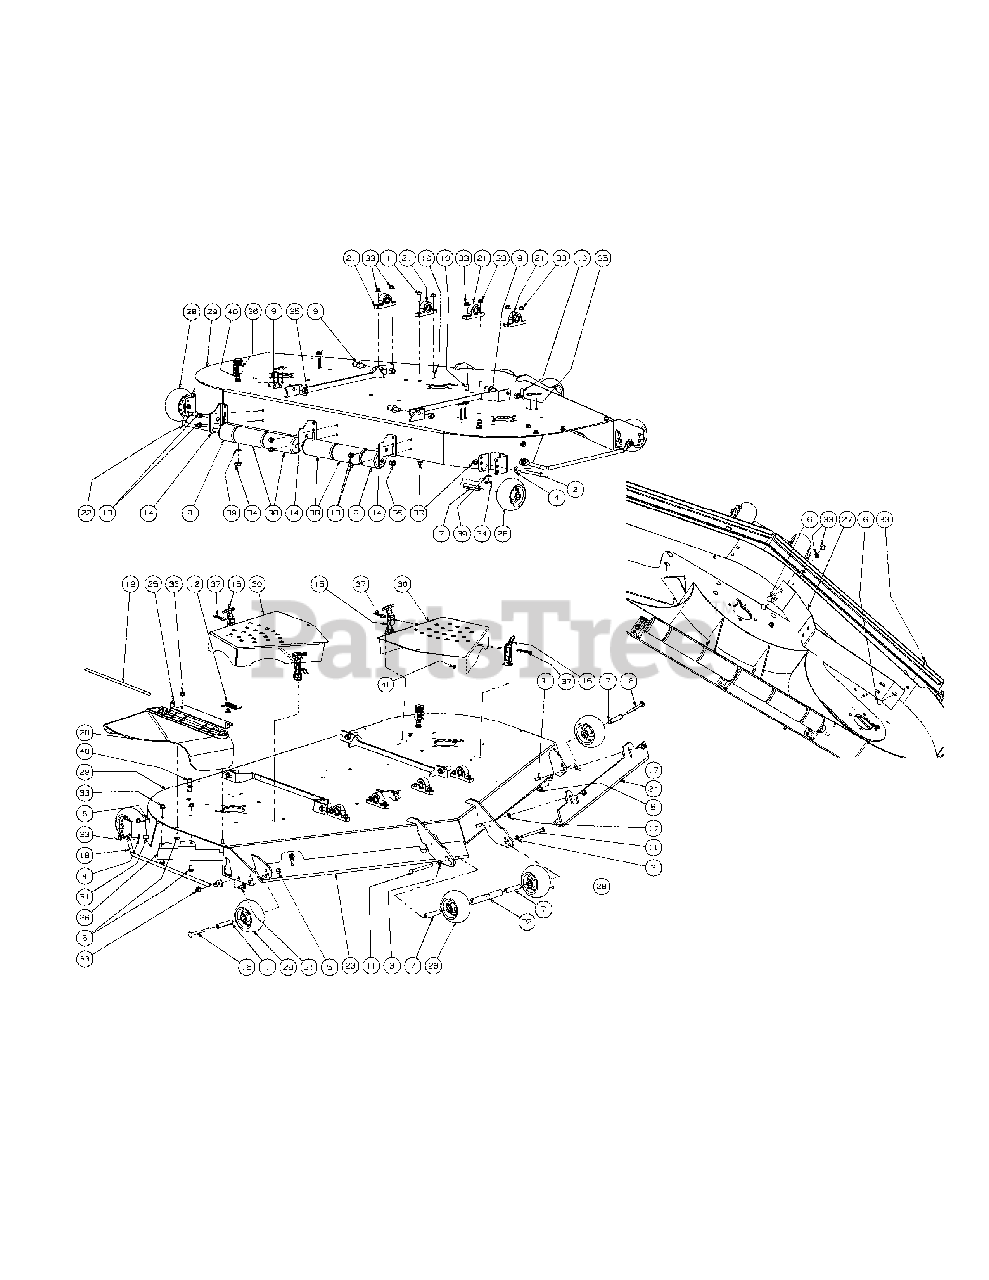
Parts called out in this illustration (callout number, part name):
1	Hex Cap Screw, 3/8-16, 1.25
2	Hex Cap Screw, 3/8-16, 4.00
3	Lock Washer, 3/8
4	Flat Washer, 3/8
5	Flange Lock Hex Nut, 3/8-16
6	Carriage Bolt, 3/8-16 x .75 Lg.
7	Wheel Spacer
8	Grass Catcher Roller
9	Pin, 5/8 Dia. x 1.2 Lg.
10	Carriage Screw, 3/8-16 x 1.25
11	Hex Cap Screw, 3/8-16 x 4.50
12	Torsion Spring, 0.4ID x 2.16Lg
13	Hex Index Washer Screw, 3/8-16, .5
14	Deck Roller Mount Bracket
15	T-Handle Latch Draw
16	Carriage Bolt, 3/8-16 x 4.00
17	Push Retainer
18	Finger Guard
19	Pin, .375 x 14.06
20	Chute Deflector
21	Pillow Block, Steel Standard
22	J-Hook w/ Threaded Roller
23	Right Hand Front Adjustment Skirt
24	Left Hand Front Adjustment Skirt
25	Chute Deflector Bracket
27	Baffle, 72" Adjustment
28	Complete Wheel, 5.00 Dia.
29	72" Deck Assembly
30	Deck Belt Cover
31	Carriage Bolt, 3/8-16 x 1
32	Ball Wheel Mounting Shaft
33	Flange Lock Hex Nut, 3/8-16
34	Hex Nut, M16-1.5
35	Lock Nut, Nylon Insert, 1/2-13
36	Water Nozzle Adaptor
37	Phillips Head Screw, #10-32 x 1/2
38	Front Roller
39	Lock Washer, 17 x 23.8 x 1.95
40	Deck Water Nozzle
41	Lock Nut, Nylon Insert, #10-32
